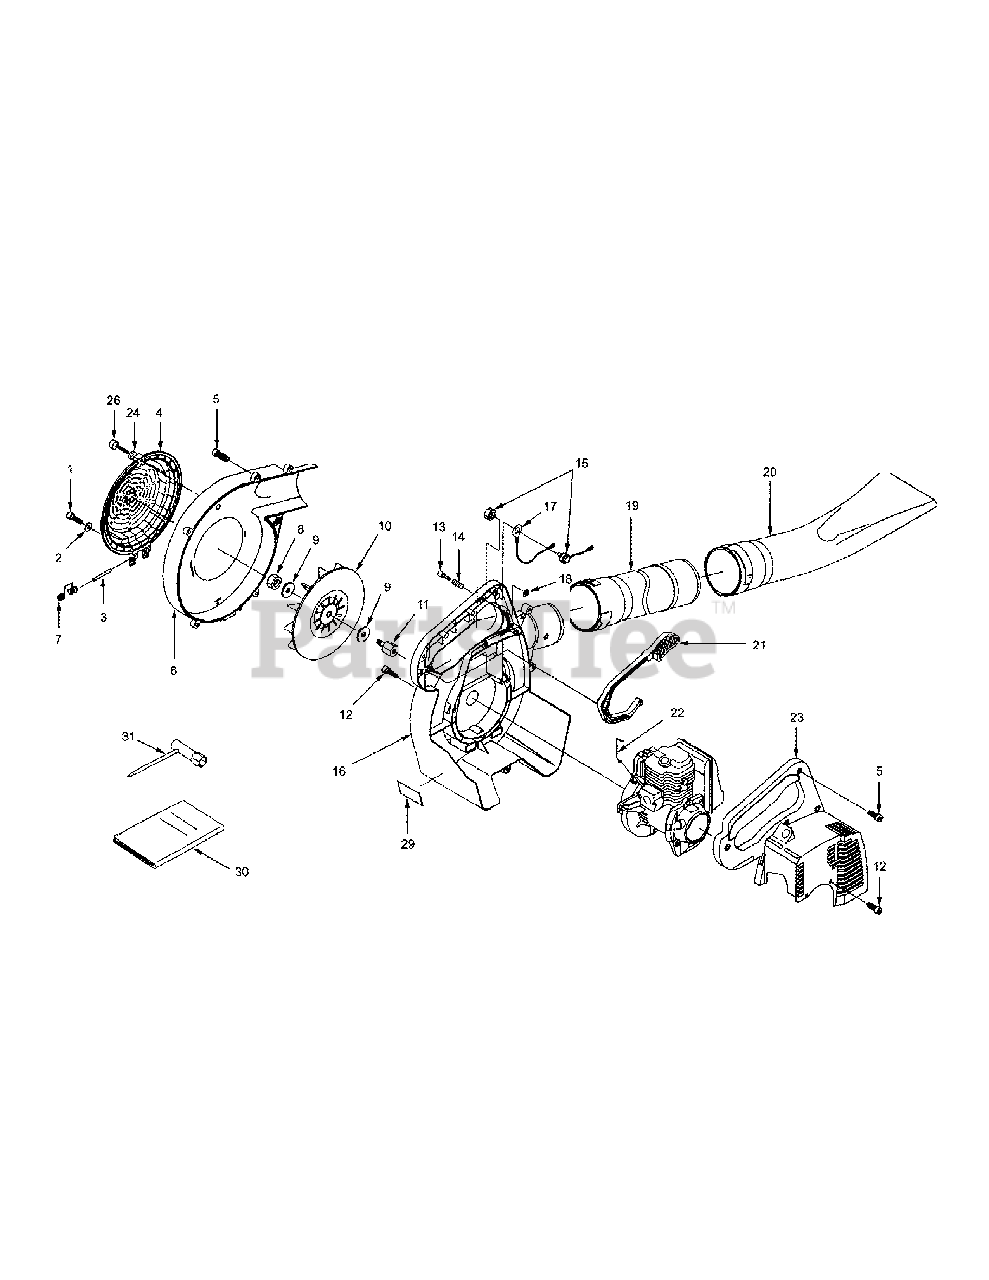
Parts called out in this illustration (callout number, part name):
1	Bolt, PC5x14
5	Bolt, PC5x18
13	Lever, Throttle
14	Spring, Throttle
15	Switch, Stop
17	Harness, Wire
18	Snap Ring, E-3
19	Pipe, Straight
21	Lever, Throttle
22	Lever, Throttle
23	Cowling, Cylinder
29	Caution Plate
30	Manual, Operator's
